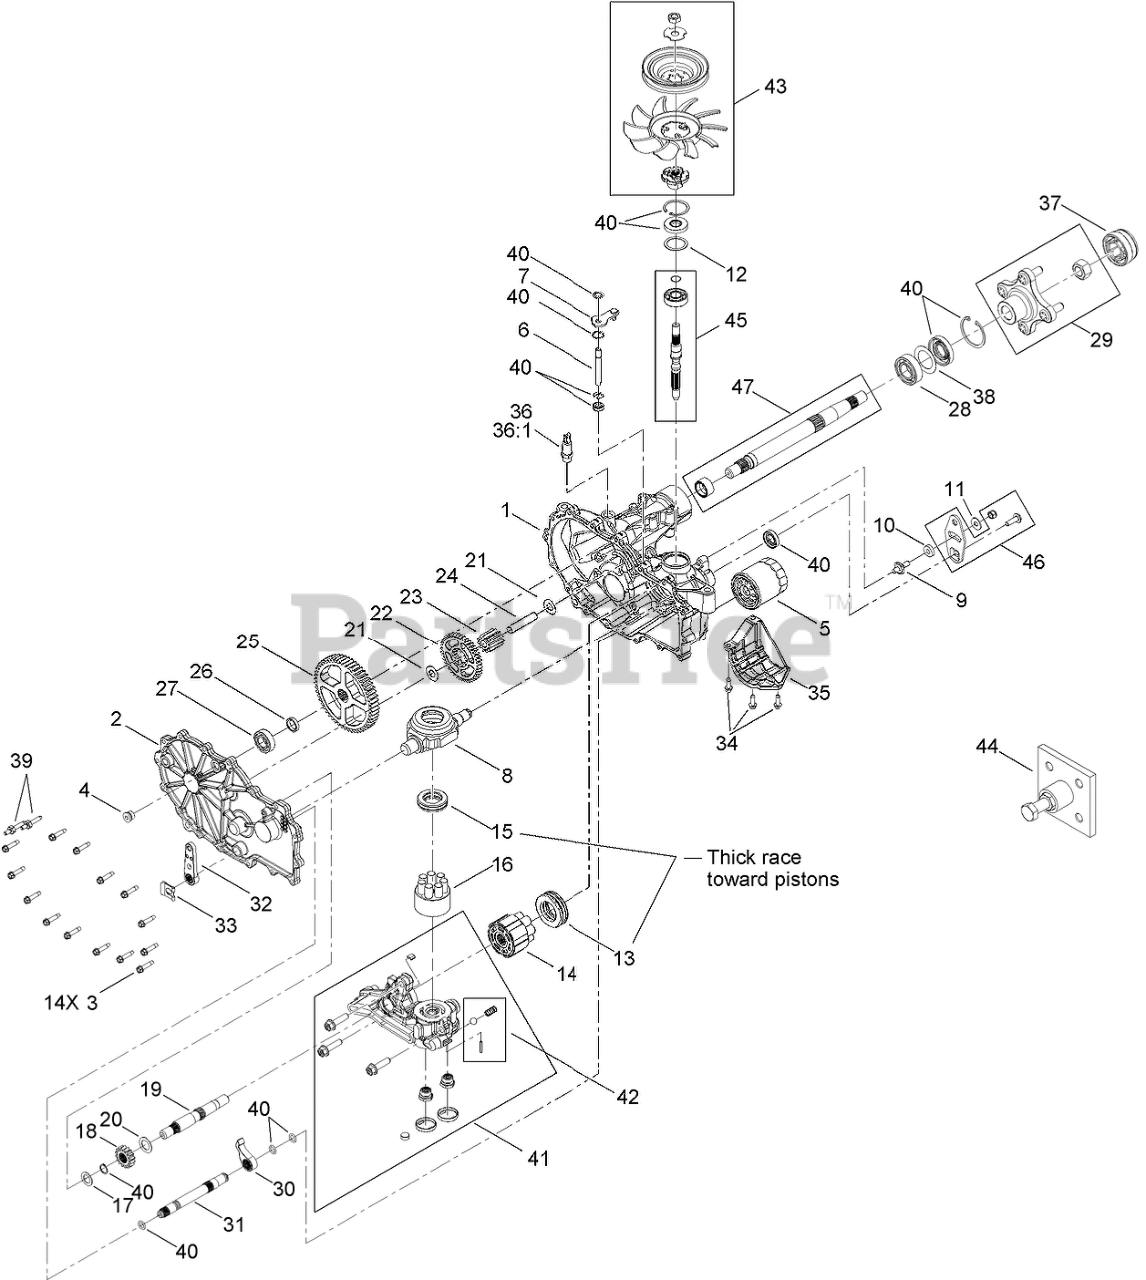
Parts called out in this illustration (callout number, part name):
1	MAIN HOUSING KIT
2	LH SIDE COVER KIT
3	SCREW-HHF
4	PLUG-THREAD, STRAIGHT
5	ELEMENT-OIL FILTER, HYD
6	ROD-BYPASS
7	ARM-BYPASS
8	SWASHPLATE-TRUNNION
10	PUCK-FRICTION
11	WASHER
12	SPACER
13	BEARING-THRUST
14	MOTOR CYLINDER BLOCK KIT
15	BEARING-THRUST
16	PUMP BLOCK ASM
17	WASHER-FLAT
18	GEAR-16T
19	SHAFT-MOTOR
20	WASHER
21	WASHER
22	GEAR-43T
23	GEAR-11T
24	PIN-JACKSHAFT
25	GEAR-54T
26	SPACER
27	BEARING-BALL
28	BEARING-BALL
29	HUB KIT
30	PAWL-BRAKE
31	SHAFT-BRAKE, INBOARD
32	HANDLE-BRAKE
33	CLIP-RETAINING
35	GUARD-FILTER, LH
36	ADAPTER-STRAIGHT
36:1	O-Ring
37	COVER-NUT, AXLE
38	SPACER
40	SEAL KIT
41	CENTER SECTION KIT
42	CHARGE RELIEF KIT
43	FAN PULLEY KIT
44	PULLER-HUB, 4 BOLT
45	INPUT SHAFT KIT
46	CONTROL ARM KIT
47	AXLE SHAFT KIT
